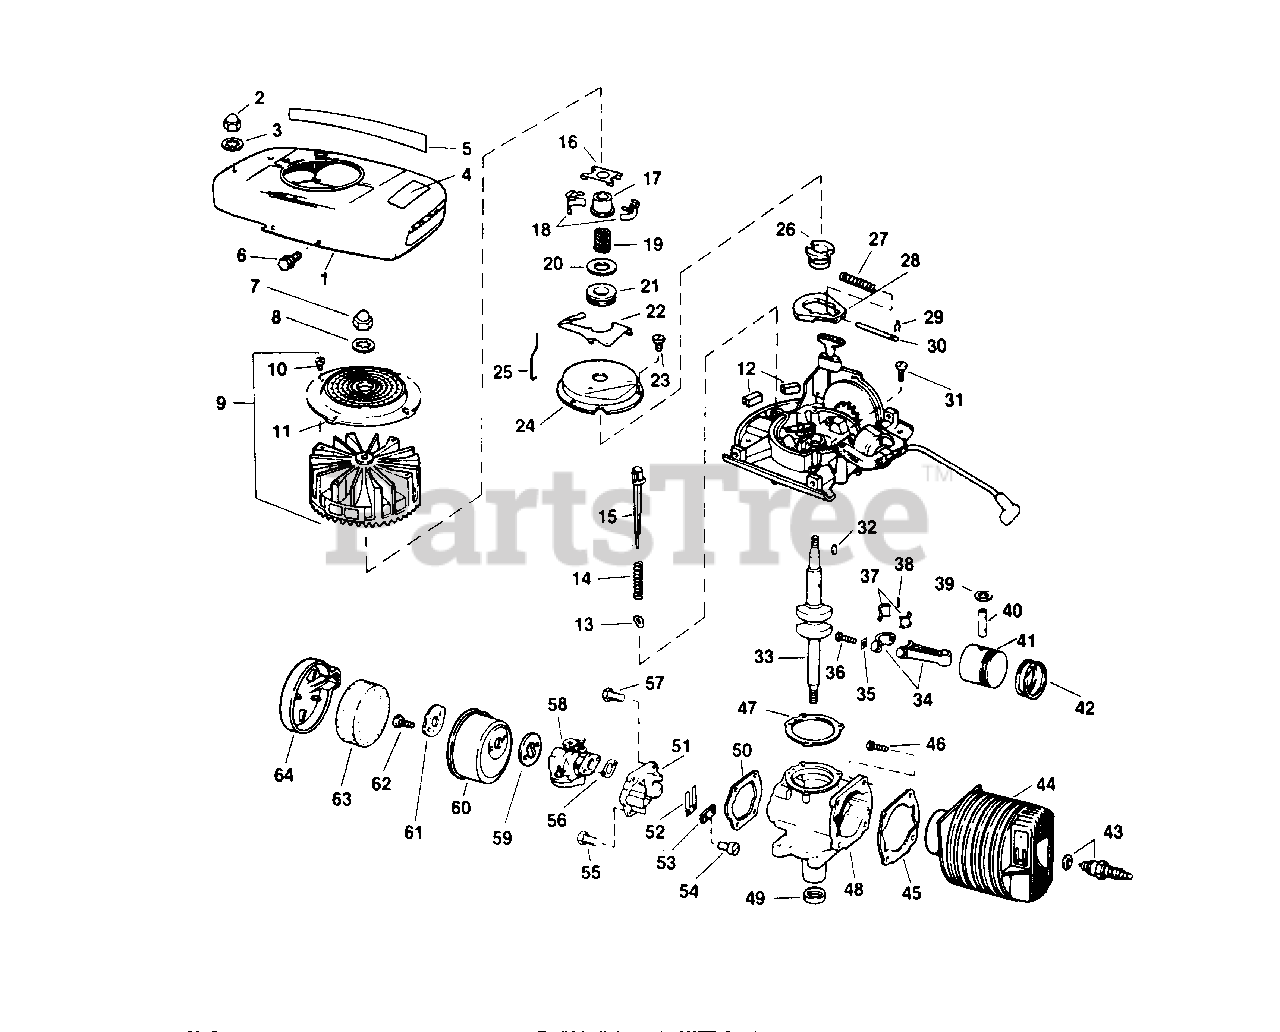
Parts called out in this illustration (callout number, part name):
1	Shroud, Tank & Shield Assy.
2	Acorn Nut
4	Decal-Instruction
5	Decal-LAWN-BOY
6	Screw-Shroud to Arm. Plate
7	Nut-Flywheel
8	Lockwasher-Flywheel
9	Flywheel and Screen Assembly
12	Pad-Rubber, Arm. Plate
13	Blade-Switch
14	Spring-Shut-Off Switch
15	Bar-Shut-Off & Primer
16	Yoke-Governor
17	Collar-Governor
18	Weight-Governor
19	Spring-Governor
20	Thrust Washer
21	Collar-Thrust
22	Lever-Governor
23	Screw-Attaching Dust Cover
24	Dust Cover
25	Rod-Governor
26	Cam-Spark Advance
27	Spring-Spark Advance
28	Flywheel-Spark Advance
29	Retainer-Spring
30	Pin-Spark Advance
31	Screw-Arm. Plate to Crankcase
32	Key-Crankshaft
33	Crankshaft
34	Connecting Rod Assy.
35	Lockplate
37	Liners-Conn. Rod
38	Needle Bearing Set
39	Retaining Ring-Wrist Pin
40	Wrist Pin
42	Ring Set (2 rings)
43	Spark Plug & Gasket Champion CJ-14, .025" Gap
44	Cylinder & Sleeve Assy.
45	Gasket-Cyl. to Crankcase
46	Screw-Mach., Cyl. to Crankcase
47	Gasket-Crkc. to Arm. Pl.-.005"
47	Gasket-Crkc. to Arm. Pl.-.010"
48	Crankcase Assy.
49	Oil Seal
50	Gasket-Reed Plate
51	Reed Plate Assembly
53	Plate-Back-Up
54	Screw-Machine
55	Screw-H.H., Reed Pl. to Crkc.
56	Gasket-Carburetor
57	Screw-H.H., Reed Pl. to Crkc.
58	Carburetor Assy.
60	Chamber
61	Washer-Back-Up
63	Element
64	Cap
